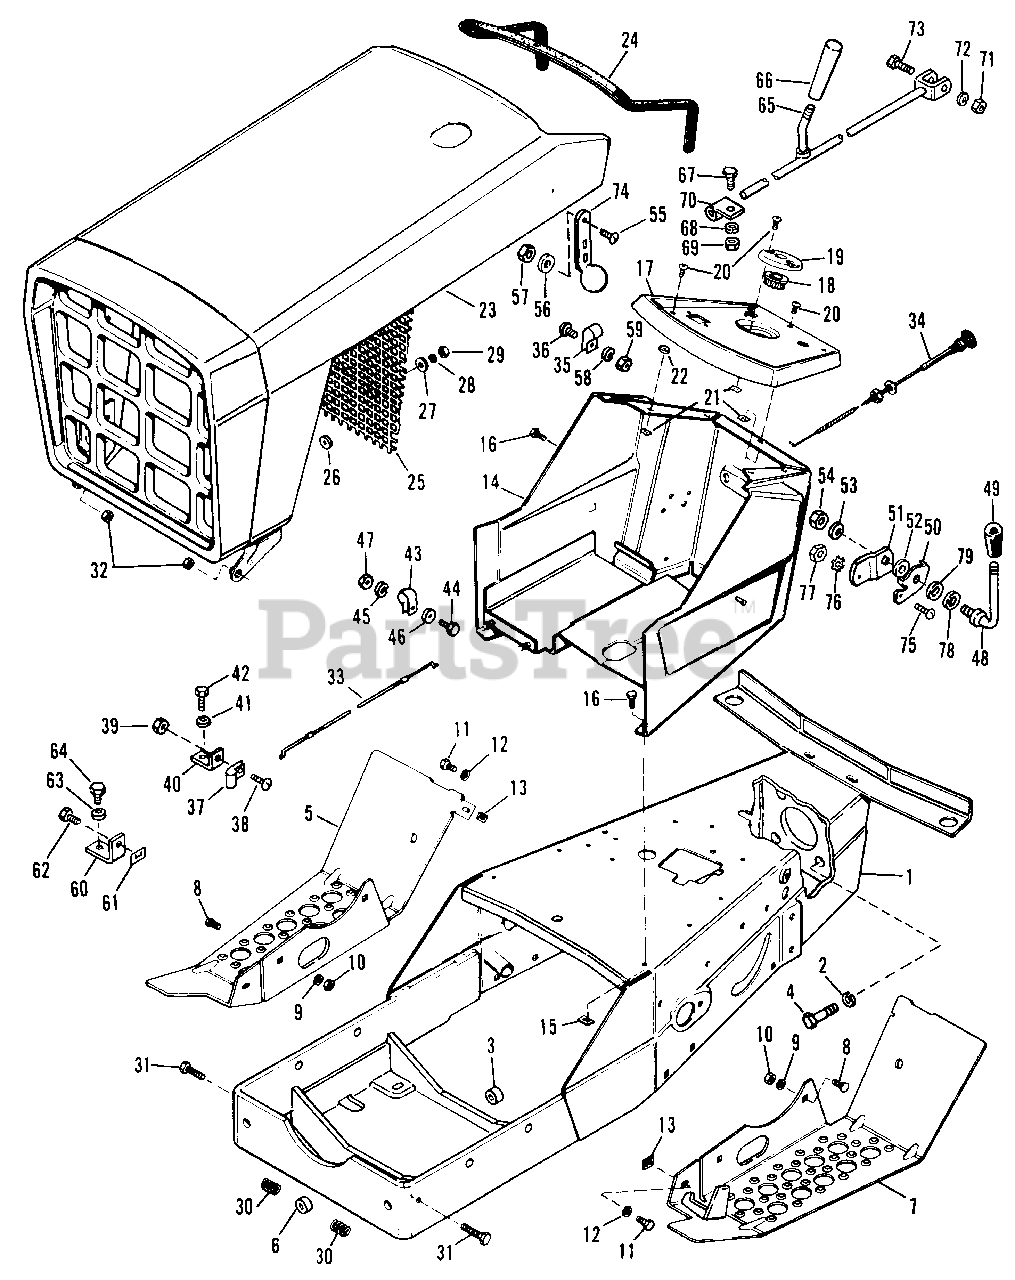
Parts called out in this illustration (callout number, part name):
1	Frame Assembly
2	Lockwasher, 7/16"
4	Hex Capscrew, 7/16"-14 N.C. x 1-1/2"
5	Foot Rest, R.H.
7	Foot Rest, L.H.
8	Carriage Bolt, 5/16"-16 N.C. x 3/4"
9	Lockwasher, 5/16"
10	Full Hex Nut, 5/16"-18 N.C.
11	Hex Capscrew, 5/16"-18 N.C. x 3/4"
12	Lockwasher, 5/16"
13	Nut, Tinnerman, 5/16"-18 N.C.
14	Dash Assembly
15	Nut, Tinnerman
16	Hex Head Self Tapping Screw, No. 14 AB x 3/4"
17	Panel, Instrument
18	Bushing, Steering
19	Plate, Steering Adj.
20	Round Head Phillips Screw, 1/4"-20 N.C. x 1/2"
21	Nut, Tinnerman, 1/4"-20 N.C.
22	Plain Washer
23	Grille & Hood Assembly
24	Molding, Hood
25	Screen, Grille
28	Lockwasher, Shakeproof No. 10
29	Full Hex Nut, No. 10-24 N.F.
31	Hex Capscrew, 3/8"-16 N.C. x 1-1/2"
32	Hex Lock Nut, Center, 3/8"-16 N.C.
33	Throttle Control
34	Choke Control
35	Clip, Bowden Wire
36	Self Tapping Rd. Hd. Screw, No. 10-24 N.C. x 1/2"
37	Clip, Bowden Wire
38	Rd. Hd. Machine Screw, No. 10-32 N.F. x 3/8"
39	Full Hex Nut, No. 10-32 N.F.
40	Bracket, Throttle Cable
41	Lockwasher, 1/4"
42	Self Tapping Rec. Hex Hd. Screw, 1/4"-20 N.C. x 5/8"
44	Hex Capscrew, 1/4"-20 N.C. x 5/8"
45	Lockwasher, 1/4"
46	Plain Washer, 1/4" Std.
47	Full Hex Nut, 1/4"-20 N.C.
48	Throttle Handle
49	Knob
50	Stop Throttle
51	Arm Throttle
53	Washer Lock Dished Type, 3/8"
54	Full Lock Hex Nut, 3/8"-16 N.C.
55	Phillips Truss Head Screw, No. 10-32 x 1/2"
57	Gripco Lock Nut, No. 10-32
58	Lockwasher, No. 12
59	Full Hex Nut, No. 10-24
60	Bracket, Pulley Guard
61	Nut, Tinnerman
62	Hex Capscrew, 1/4"-20 x 3/4"
63	Plain Washer, 3/16"
64	Hex Head Screw, No. 14 x 1-1/4"
65	Shifter Rod Assembly
67	Hex Capscrew, 5/16"-18 x 1-1/2"
68	Lockwasher, 5/16"
69	Full Hex Nut, 5/16"-18
70	Shift Rod Guide Assembly
71	Full Hex Nut, 1/4"-20
72	Lockwasher, 1/4"
73	Hex Capscrew, 1/4"-20 x 5/8"
75	Round Head Machine Screw, No. 10-32 x 1/2"
76	Lockwasher, Shakeproof No. 10
77	Full Hex Nut, No. 10-32
